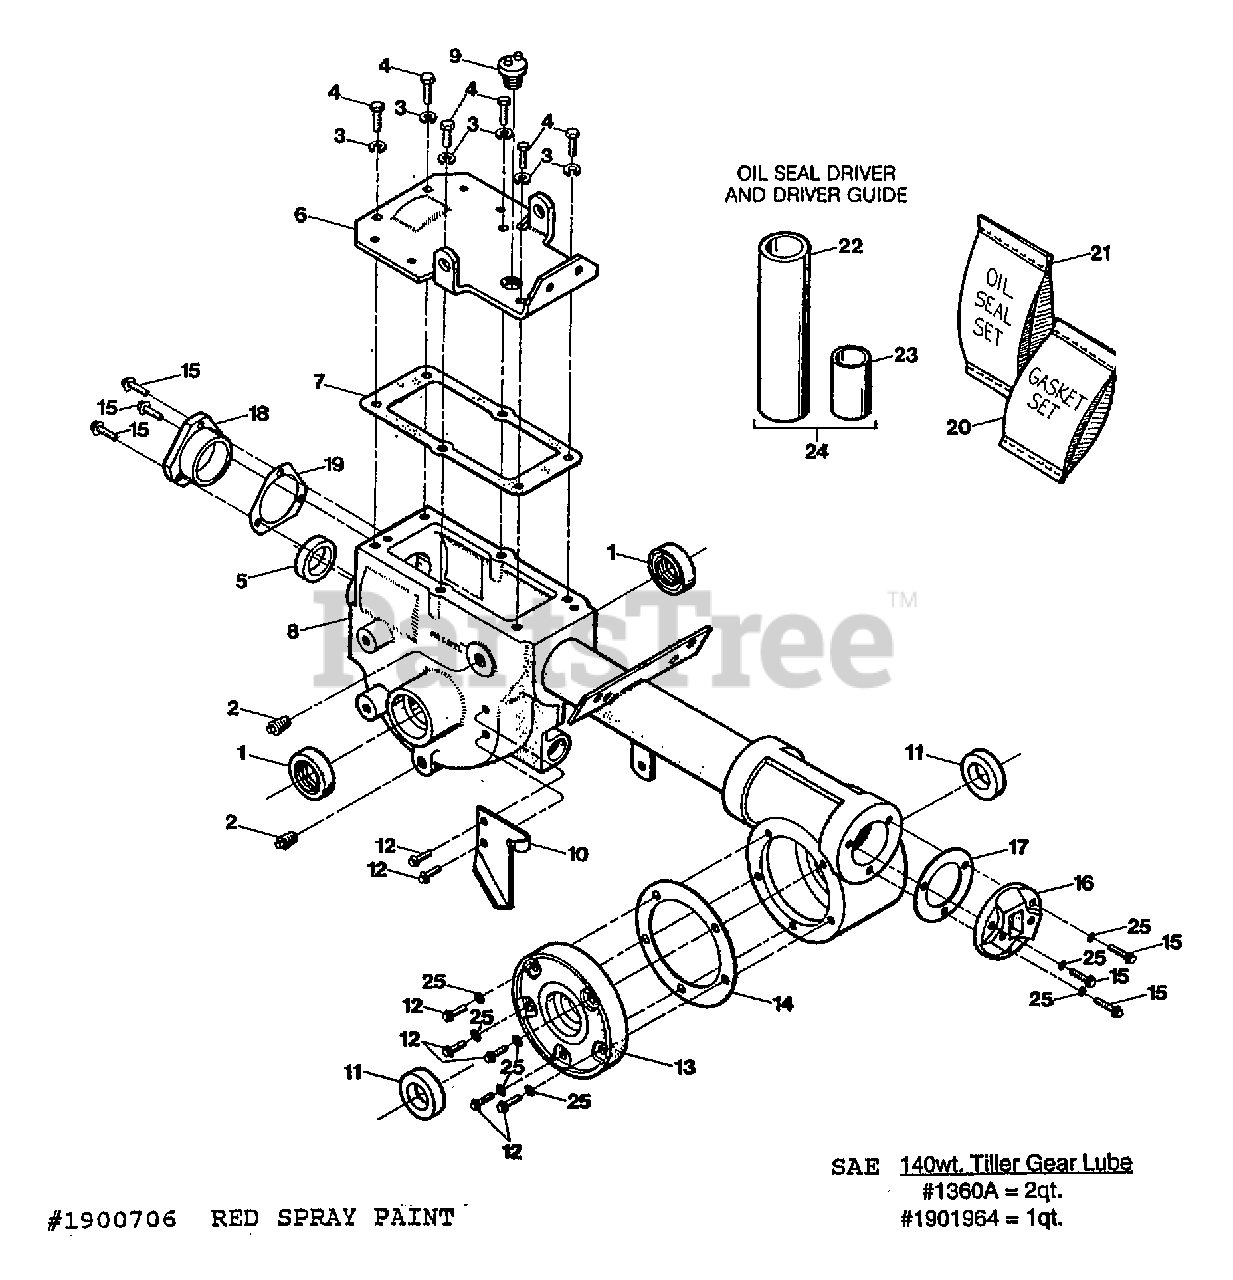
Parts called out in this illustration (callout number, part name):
1	SEAL-OIL WHEELSHAFT
2	PLUG-PIPE 1/4 NPT
3	WASHER-LK .312 ZP
4	SCR-HHC 5/16-18X.75 GR 5 ZP
5	SEAL-PINION SHAFT PT/85030/00
6	COVER-TRANS
7	GASKET-TRANS COVER
8	HSG-TRANS P5 A UNIT (INCL. ONE #9429)
9	PLUG-OIL FILL 3/4-10
10	PLATE-CABLE MOUNT PNT (FOR WHEEL DRIVE CABLE)
11	SEAL-TILLER SHAFT
12	SCR-HH 1/4-20X.625
13	COVER-RTH W/SCRS&RACE
14	GASKET-TILLER COVER (FITS ALL COVERS)
15	SCR-HFLK 1/4-20X.875
16	CAP-REAR #1115
17	GASKET-BRG COVER
18	COVER-FRONT BEARING
19	GASKET-FRONT COVER-.010
20	GASKET SET-P4
21	OIL SEAL SET-PONY V
22	DRIVER-PLASTIC (USE WITH PART #4921-2)
23	SEAL-DRIVER PILOT (USE WITH PART #4921-1)
24	KIT-DRIVER (INCL. 22,23)
25	WASHER - NYLON, NOR REUSABLE
